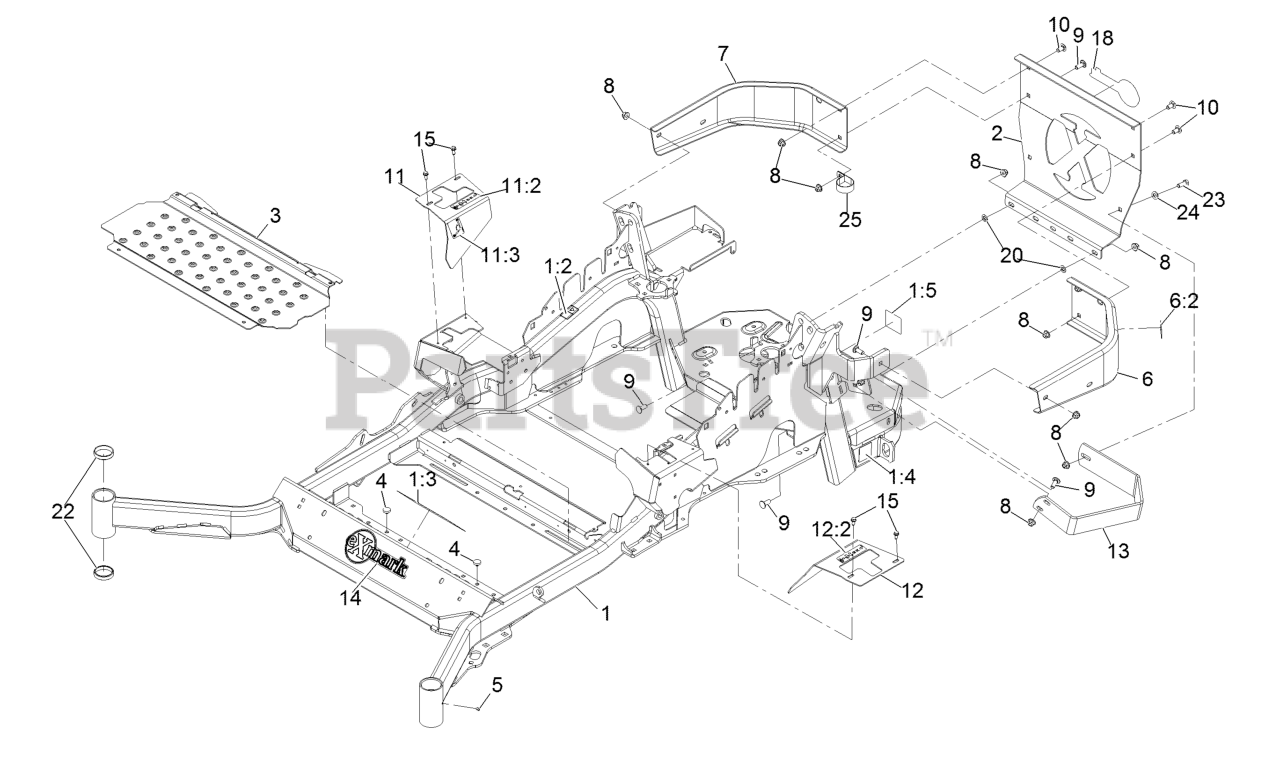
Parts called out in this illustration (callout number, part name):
1	Mainframe ASM
1:2	Decal-Warning
1:3	Decal-Danger
1:4	Decal-Hazard, Pinched Finger
1:5	Decal-Spark Arrester
2	Plate,Rear Guard
6	LH Bumper ASM
6:2	Decal-Warning
7	Bumper-RH
8	Nut-Nyloc 3/8-16 Flg
9	Bolt-Carriage 3/8-16 X 1
10	Bolt-Carriage 3/8-16 X 3/4
11	RH Motion Control Cover ASM
11:2	Decal-Control, Motion
11:3	Decal-Park Brake, CE
12	LH Motion Control Cover ASM
12:2	Decal-Control, Motion
13	Guard-Muffler
14	Decal-Exmark
15	Screw-HWH 1/4-20 X .62
18	Decal-Exmark Logo
20	Nut-Push 3/8-16
22	Cup-Bearing Tapered Roller
23	Screw-HH 3/8-16 X 1
24	Washer-3/8 SAE
